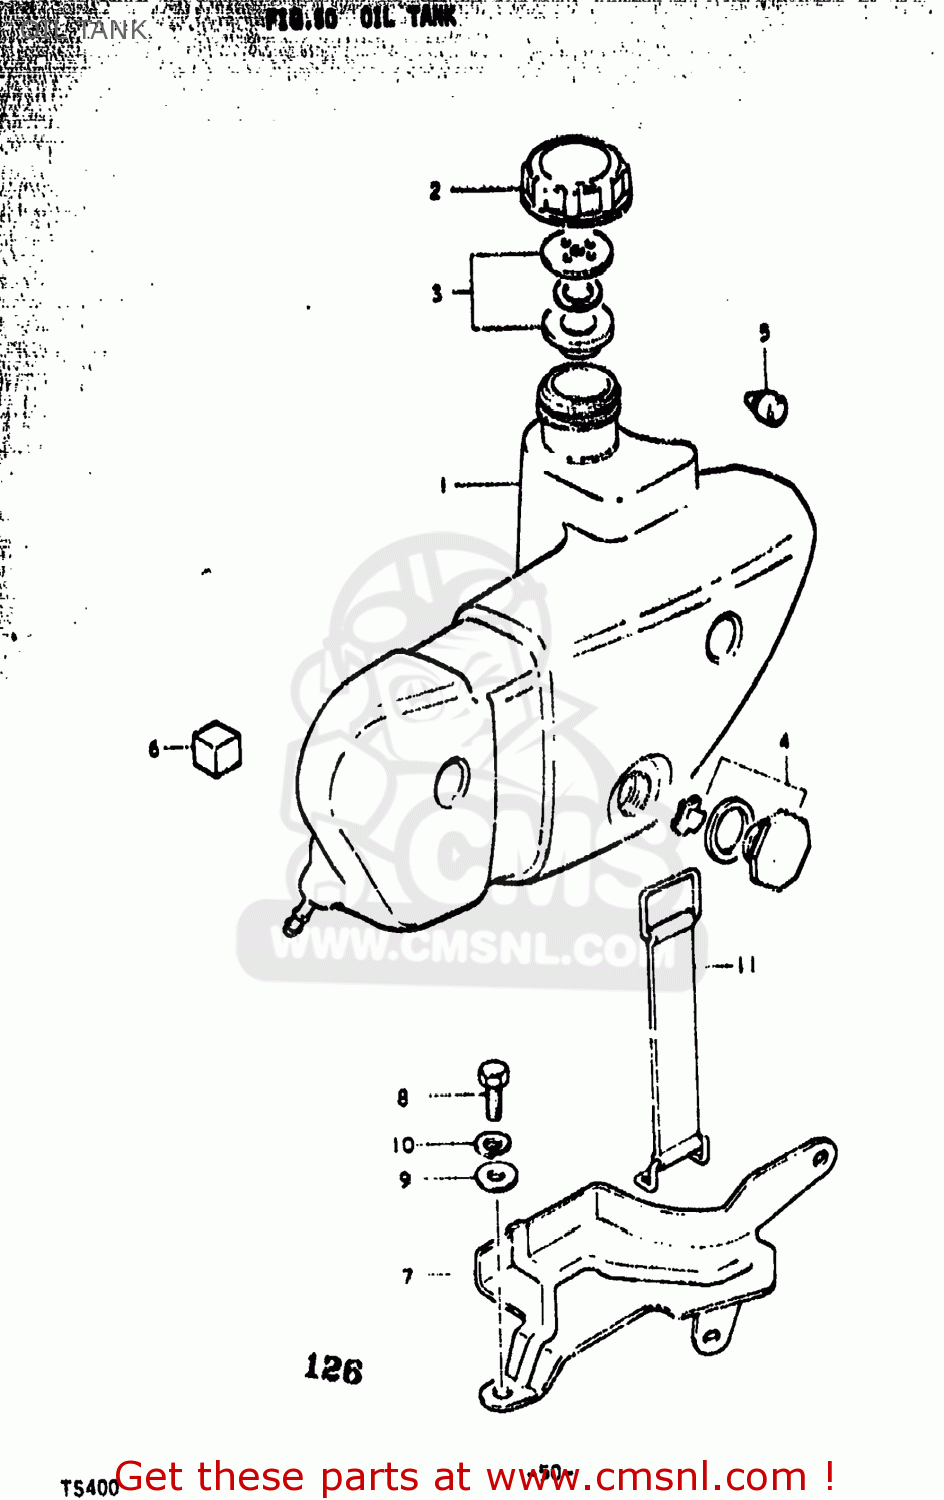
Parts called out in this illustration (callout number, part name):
1	TANK,OIL
2	CAP,OIL TANK
3	GASKET SET,OIL TANK CAP
4	LENS SET,OIL LEVEL
5	CUSHION
7	HOLDER, OIL TANK
8	BOLT
9	WASHER
10	LOCK WASHER
11	BAND
